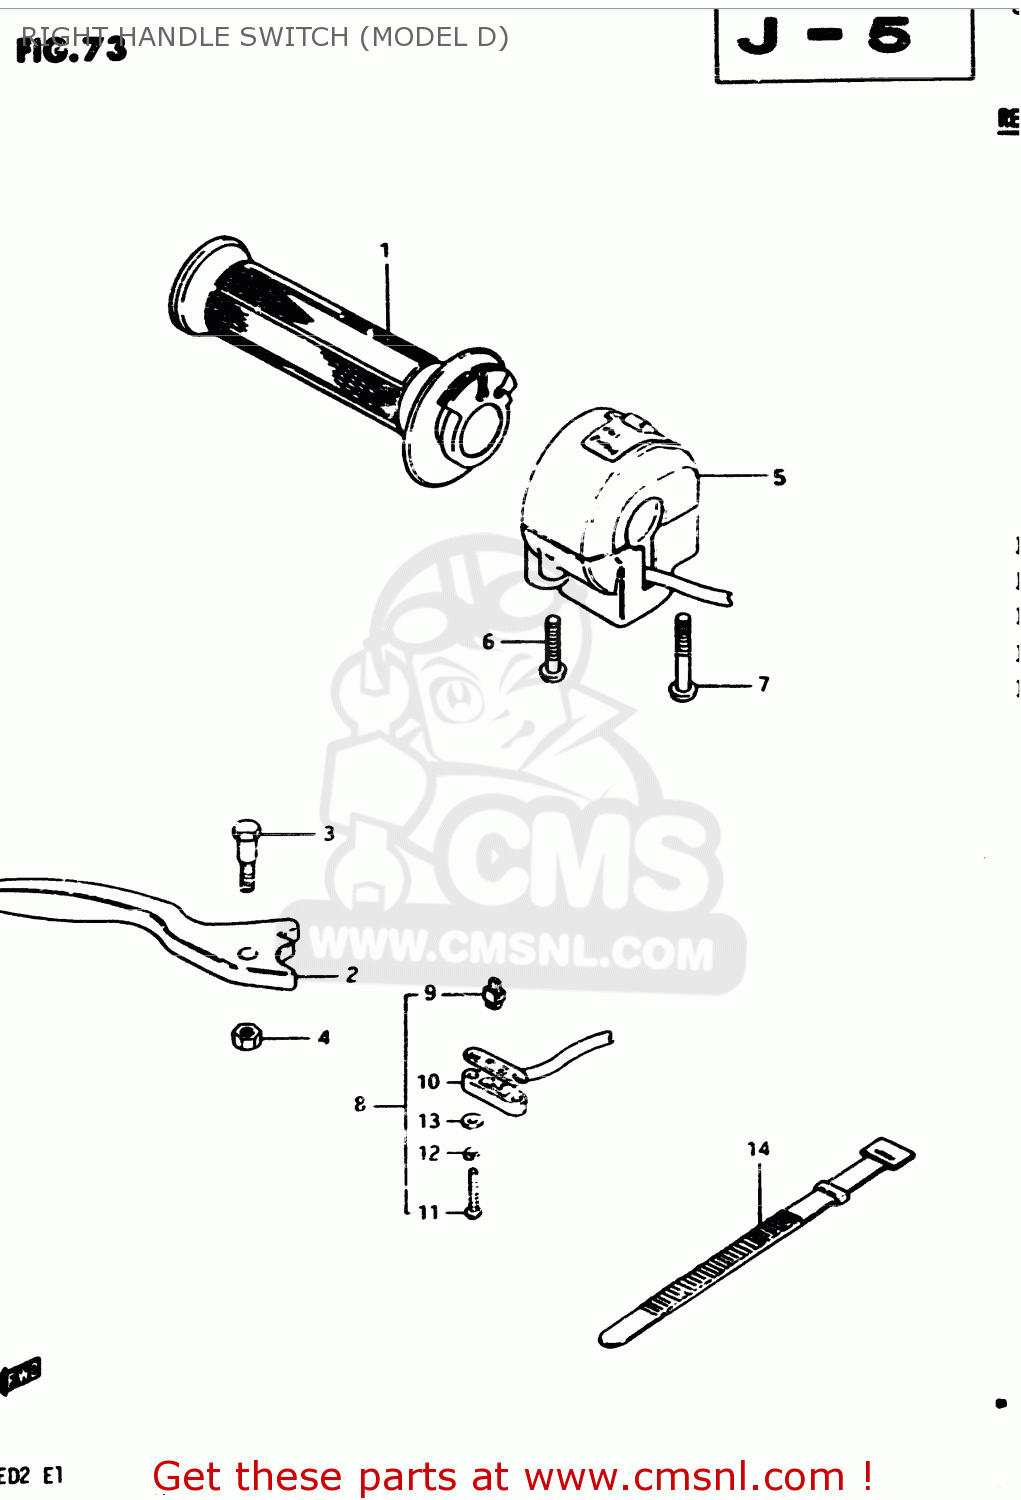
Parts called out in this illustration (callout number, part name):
1	GRIP,THROTTLE
2	LEVER,BRAKE
3	BOLT
4	NUT 6MM
5	SWITCH ASSY, HANDLE LH
6	SCREW
7	SCREW
8	SWITCH ASSEMBLY
9	CONTACT,SWITCH
10	COVER,FR BK TERMINAL BASE
11	SCREW
12	LOCK WASHER
13	WASHER
14	CLAMP(L:120)
